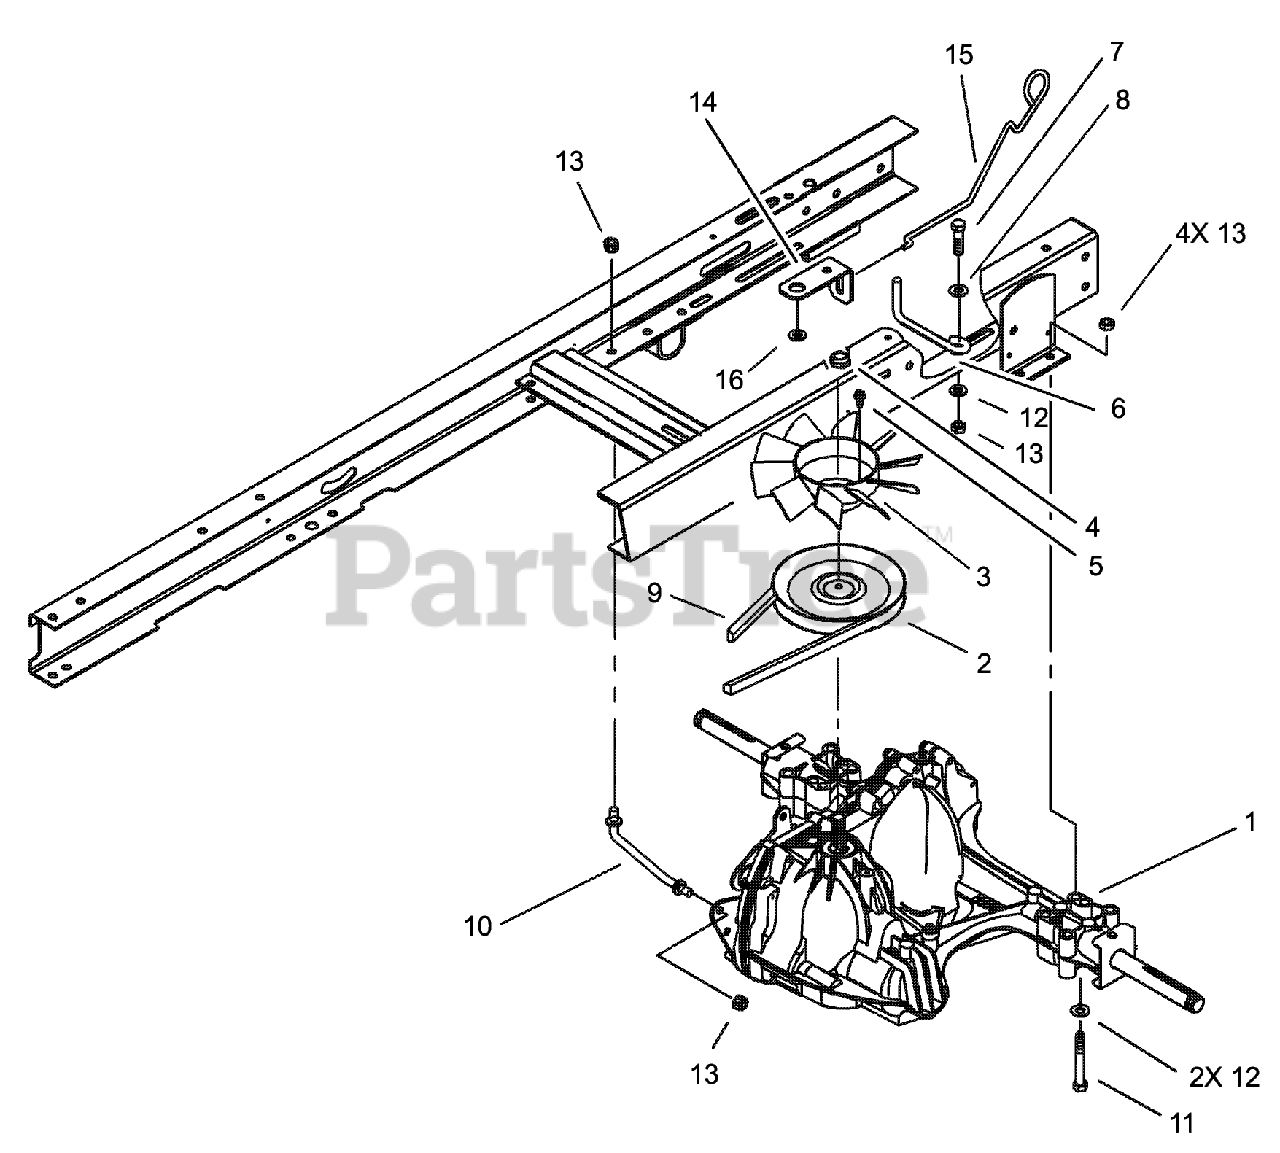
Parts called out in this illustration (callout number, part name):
1	TRANSAXLE ASM
2	PULLEY
4	NUT-LOCK, NI
5	SCREW-HWH
6	GUIDE-BELT
7	SCREW-HH
8	WASHER-PIVOT
9	V-BELT
10	STRAP-TORQUE
11	SCREW-HH
12	WASHER-PLAIN
13	NUT-LOCK, NI
14	BRACKET-BYPASS
15	ROD-BYPASS
16	WASHER-FLAT
